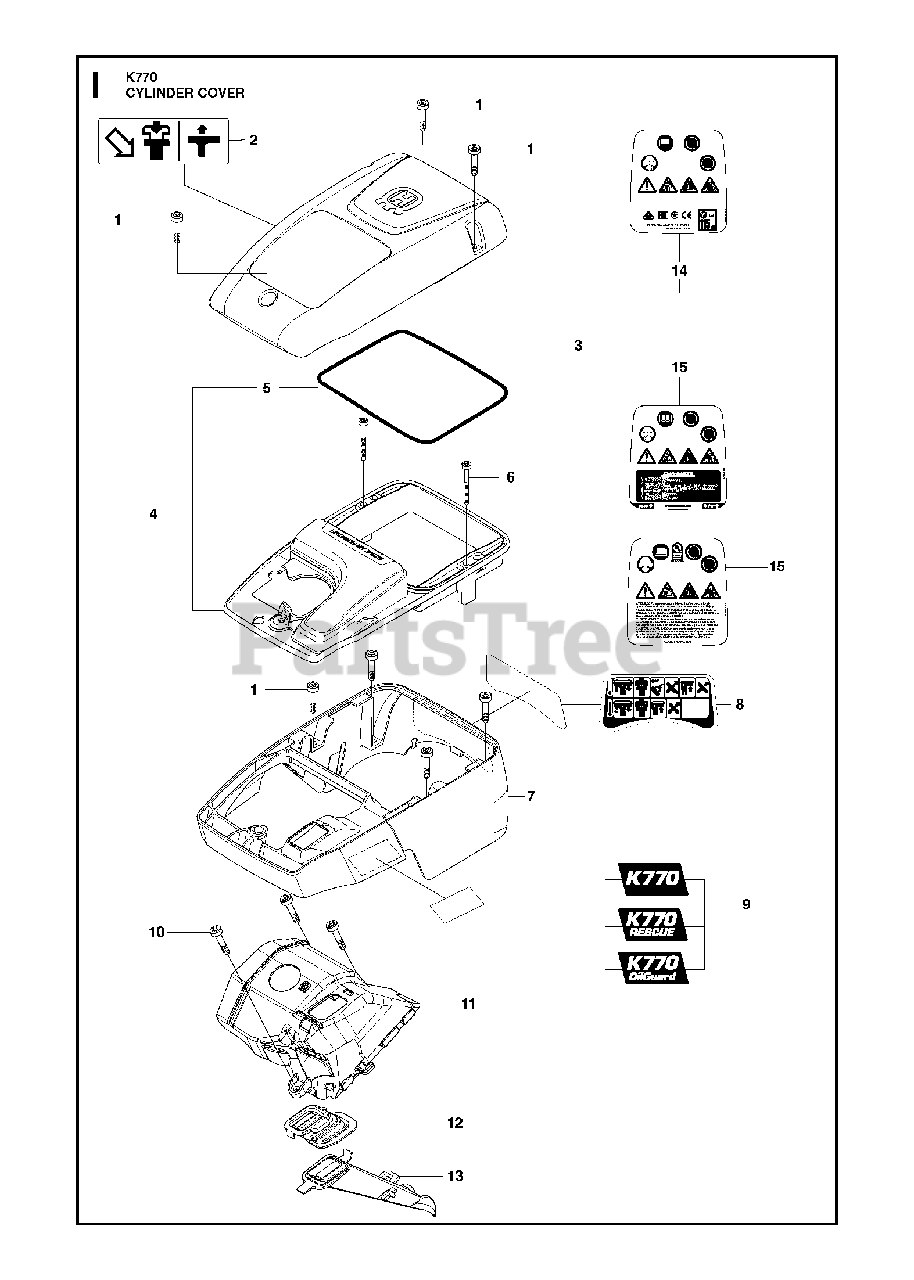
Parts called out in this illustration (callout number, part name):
1	SCREW ITXSCM
3	FILTER COVER ASSYincl. 14
4	FILTER HOLDER ASSYIncl. 5
4	FILTER HOLDER ASSYIncl. 5. OIL GUARD
5	SEALING STRIP
6	SCREW ITXSCM
7	CYLINDER COVER
10	SCREW ITXSCM
12	BELLOWS
